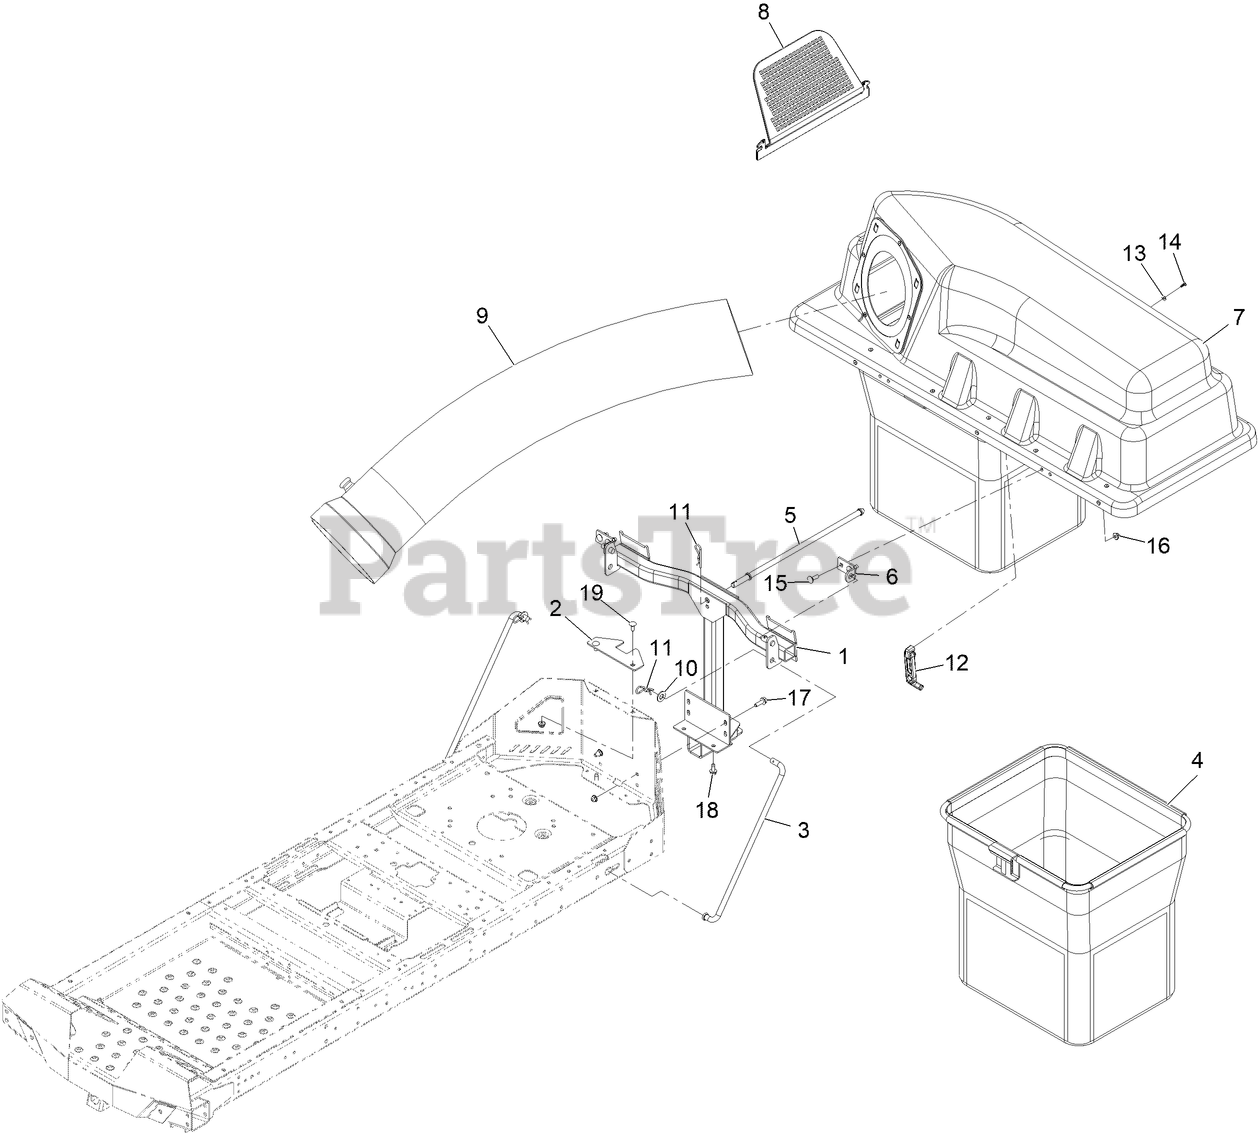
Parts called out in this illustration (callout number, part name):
1	Frame ASM, Pivot [black]
2	BRACKET-STABILIZER
3	ROD-SUPPORT, CZ
4	BAG ASM
5	ROD-HOOD, DOWN (HOLD)
6	BRACKET-HOPPER PIVOT
7	Top ASM-Bagger
8	SCREEN-BAGGER
9	TUBE-BAGGER
10	WASHER-FLAT
11	PIN-HAIR
12	LATCH-RUBBER
13	Washer-Plain
14	SCREW-PLASTIC, PTH
15	Bolt-CARR
17	SCREW-HHF
18	Screw-HWH 5/16-18 X 3/4 Tf
19	BOLT-CARR
